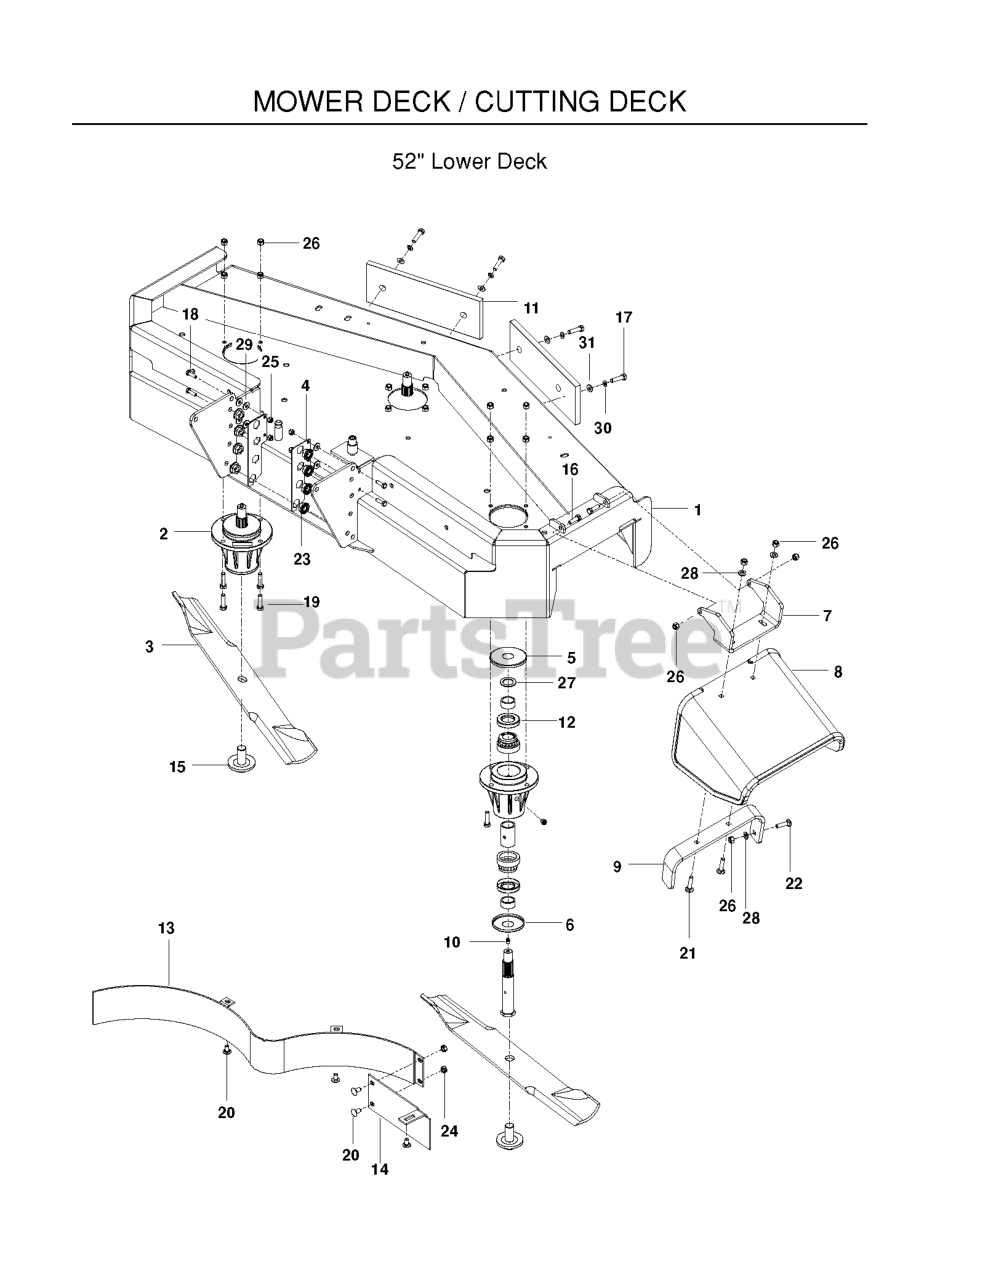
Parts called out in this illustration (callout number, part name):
1	DECK SVC W/DECALS WH5218
2	HOUSING ASM, 72
3	BLADE OEM 18"
4	PLATE NUT - PAINTED
5	TOP DUST CAP
6	BOTTOM DUST CAP
7	HINGE CHUTE - BLACK
8	CHUTE, RUBBER DISCHARGE WB
9	BRKT, REINF-CHUTE WB
11	WEIGHT, COUNTER, ORANGE
12	SHAFT SEAL
13	MAIN BAFFLE 52"
14	CENTER BAFFLE - 52"
15	BLADE BOLT/WASHER
16	HCS 5/16C X 1
17	HCS 1/2-13 X 1-1/2 GR 5 ZD
18	HCS 1/4-20X7/8 GR5
19	HCS 5/16C X 1 1/4
20	CARRIAGE BOLT 5/16C X 5/8"
21	RHSNB 5/16-18 X 1-1/2 GR 5 ZD
22	BOLT, CARRIAGE 5/16X1-1/4
23	NUT FLANGE 1/2-13 GR 5
24	5/16-18 NYLOC FLANGE NUT
25	NUT.1/4-20.HEX.NYLOC.ZD
26	NUT 5/16 NYLOC
27	MACHINE BUSHING
28	FLAT WASHER 5/16 SAE
29	WASHER 1/4 FLAT
30	WASHER 1/2" SPLIT LOCK
31	WASHER 1/2" FLAT
